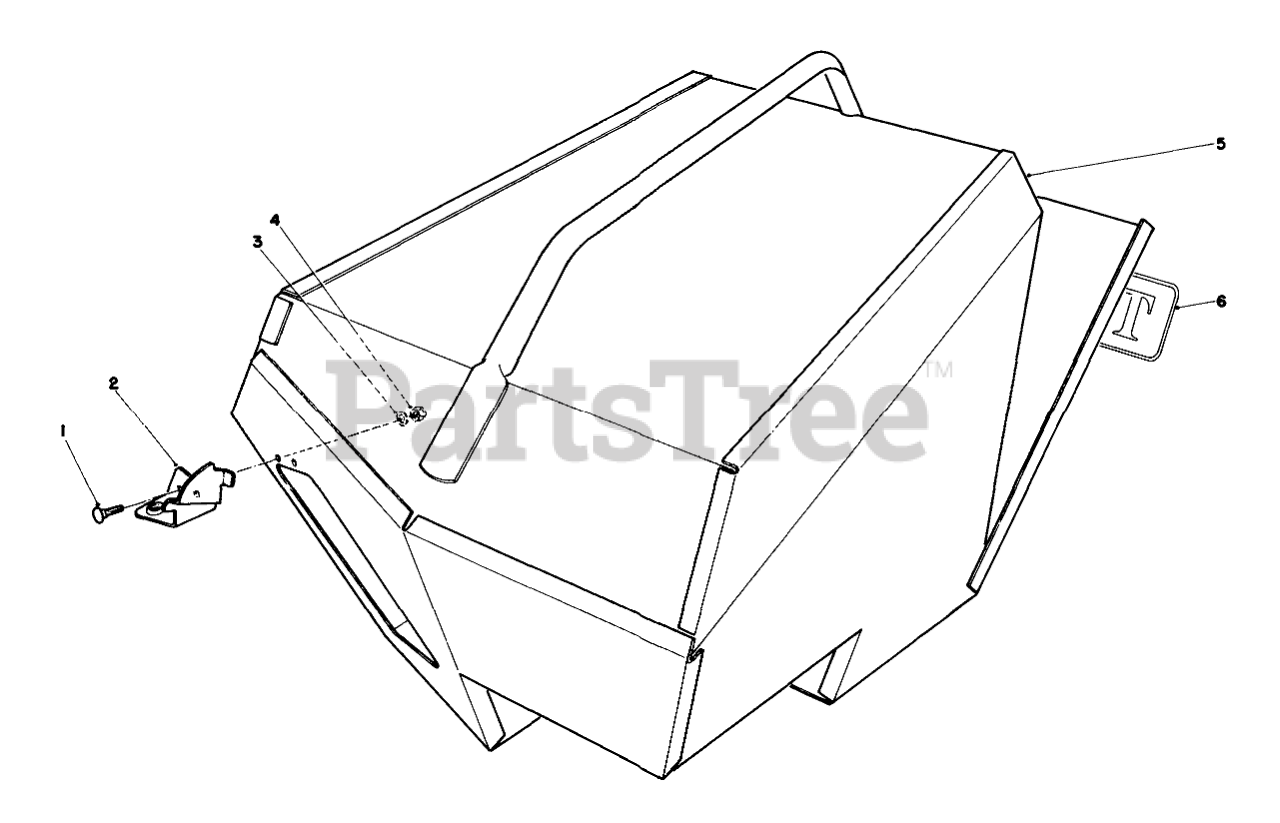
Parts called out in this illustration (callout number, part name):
1	SCREW-CARR
2	Bracket-Latch
3	WASHER-FLAT
4	NUT-LOCK, NI
5	Bag-Steel
6	Decal
